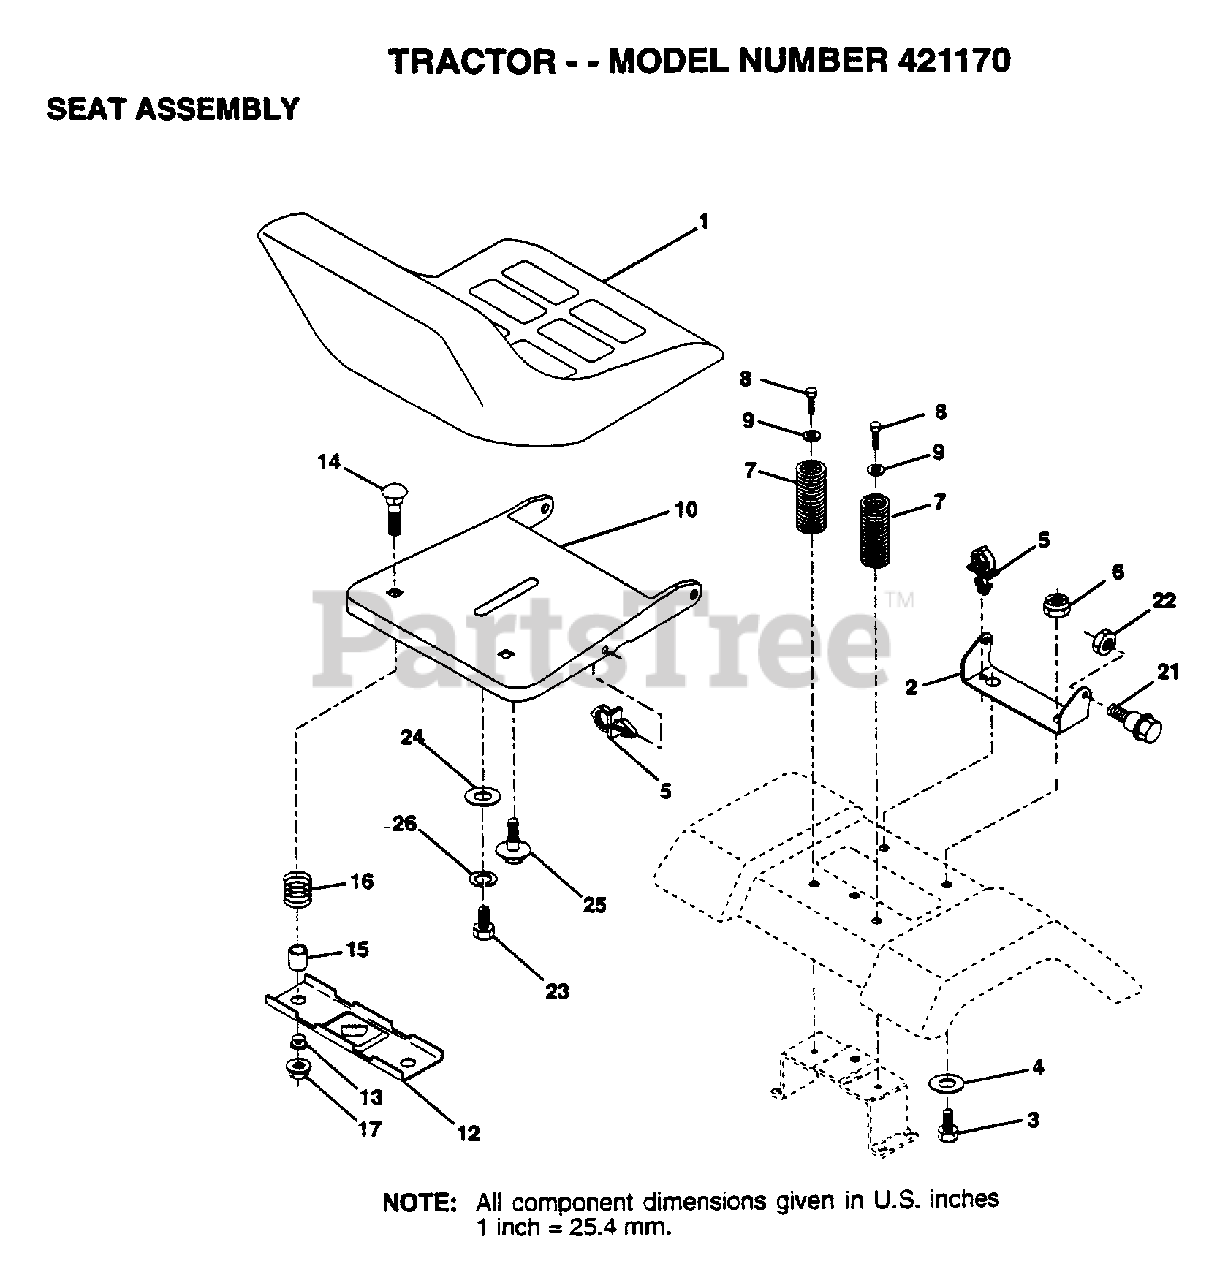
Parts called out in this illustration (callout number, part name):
2	BRACKET PVT SEAT
3	BOLT
4	WASHER PM
5	CLIP.PUSH-IN.HING
6	NUT
7	SPRING COMPRESSIO
8	SCREW GTV
9	WASHER
12	BRKT SWITCH
13	BUSHING
15	SPLIT SPACER
16	SPRING
21	BOLT.SHLD.5/16-18
22	NUT
23	BOLT
24	WASHER
25	"BOLT,SHOULDER"
26	LOCKWASHER
